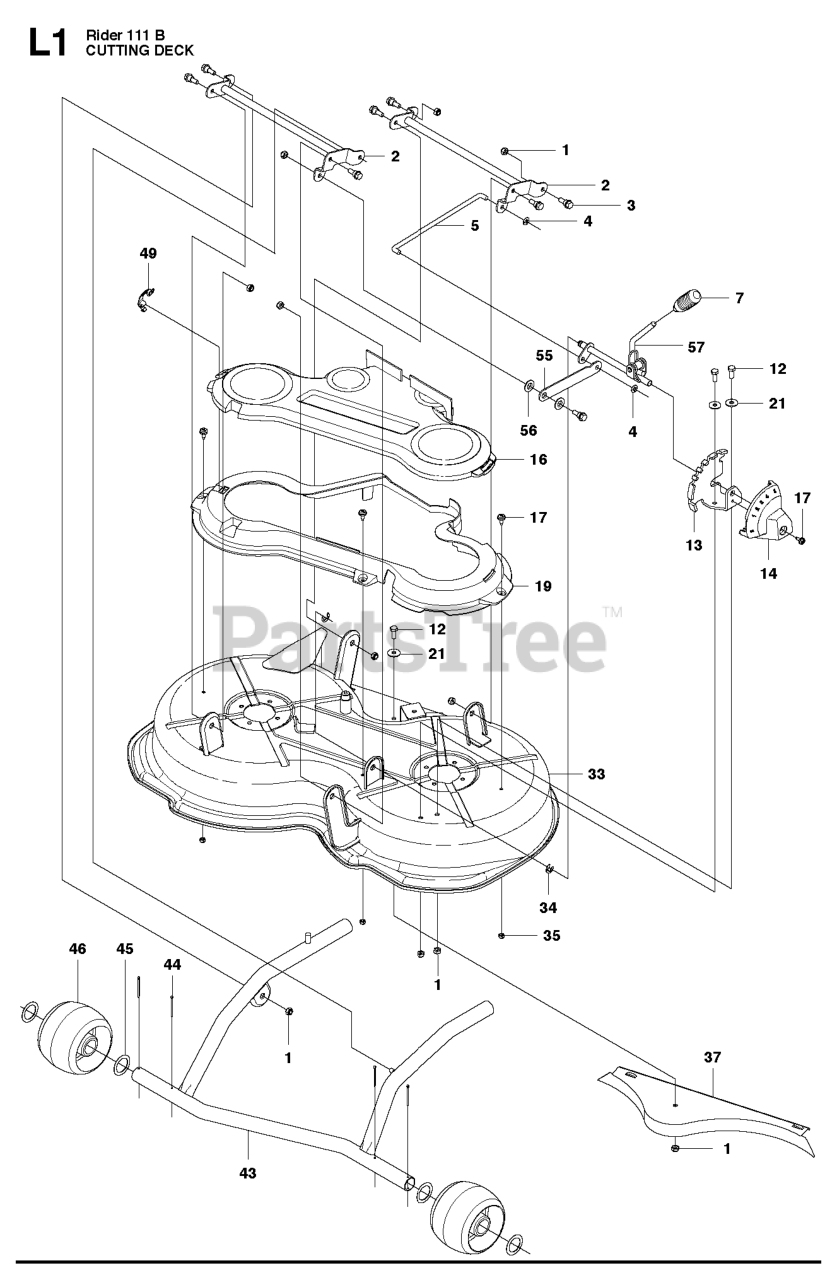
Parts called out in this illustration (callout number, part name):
1	LOCKNUT M8
34	RETAINING RING
35	LOCKNUT M6
44	COTTER PIN
49	BUCKLE ORANGE
56	WASHER - 25X8.5X2.3
